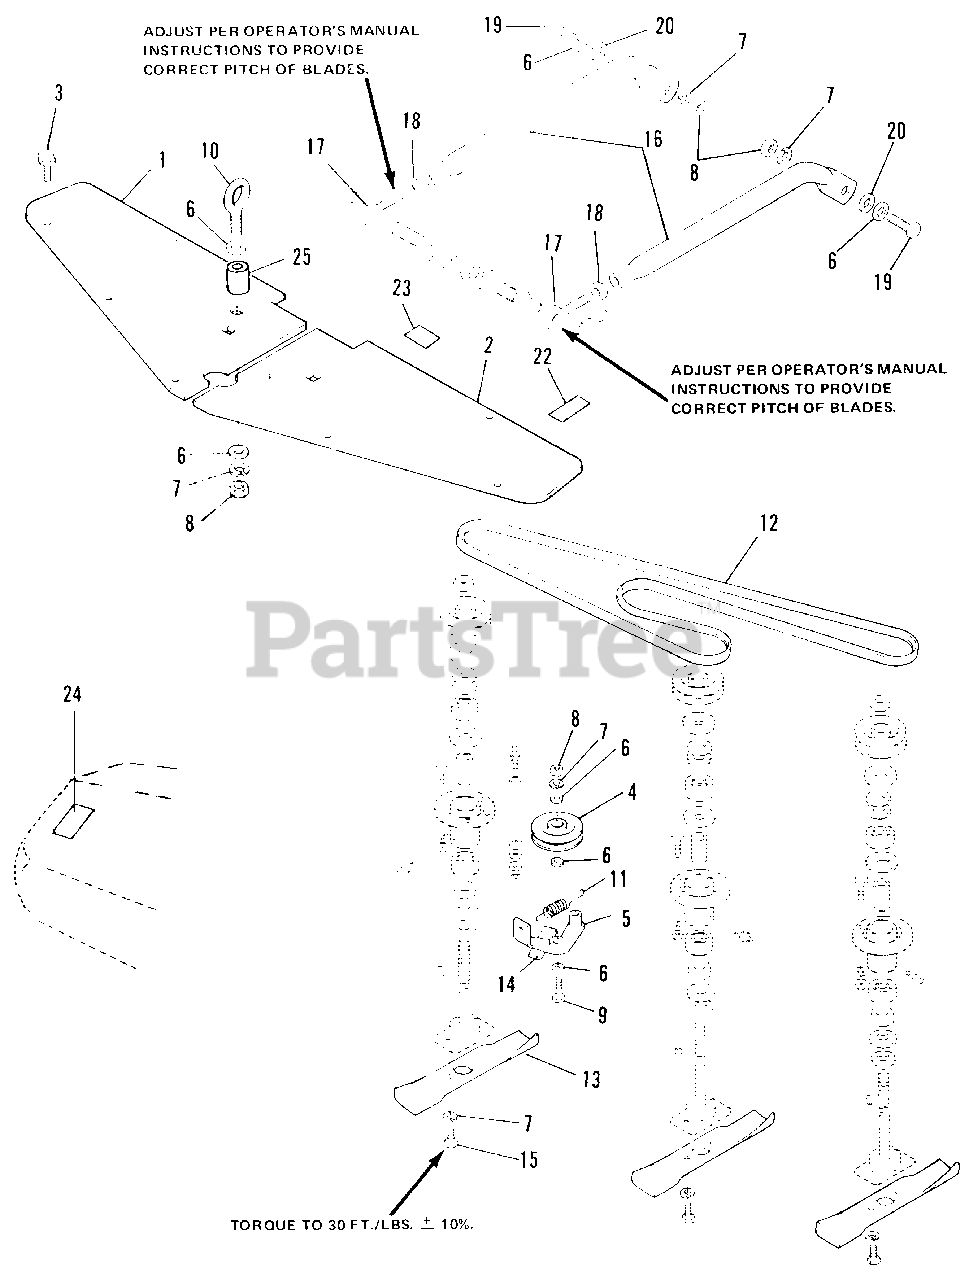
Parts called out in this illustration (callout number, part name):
1	COVER, R.H.
2	COVER, L.H.
3	SCREW, Hex Hd., Self-Tapping, 1/4-20 x 3/8
4	PULLEY, Idler
5	LEVER ASSY, Idler
6	WASHER, Plain, 5/16
7	LOCKWASHER, 3/8
8	NUT, Hex Full, 3/8-16
9	CAPSCREW, Hex Hd., 3/8-16 x 1-1/4
12	"V" BELT, Blade Drive
14	GASKET, Felt
15	CAPSCREW, Hex Hd, 3/8-16 x 5/8
16	ARM, Adjusting
18	NUT, Hex Jam, 1/2-20
19	CAPSCREW, Hex Hd., 3/8-16 x 1
21	FlLM, Safety
22	FILM, Belt Installation
23	DECAL, Caution
24	RACE, Inner
